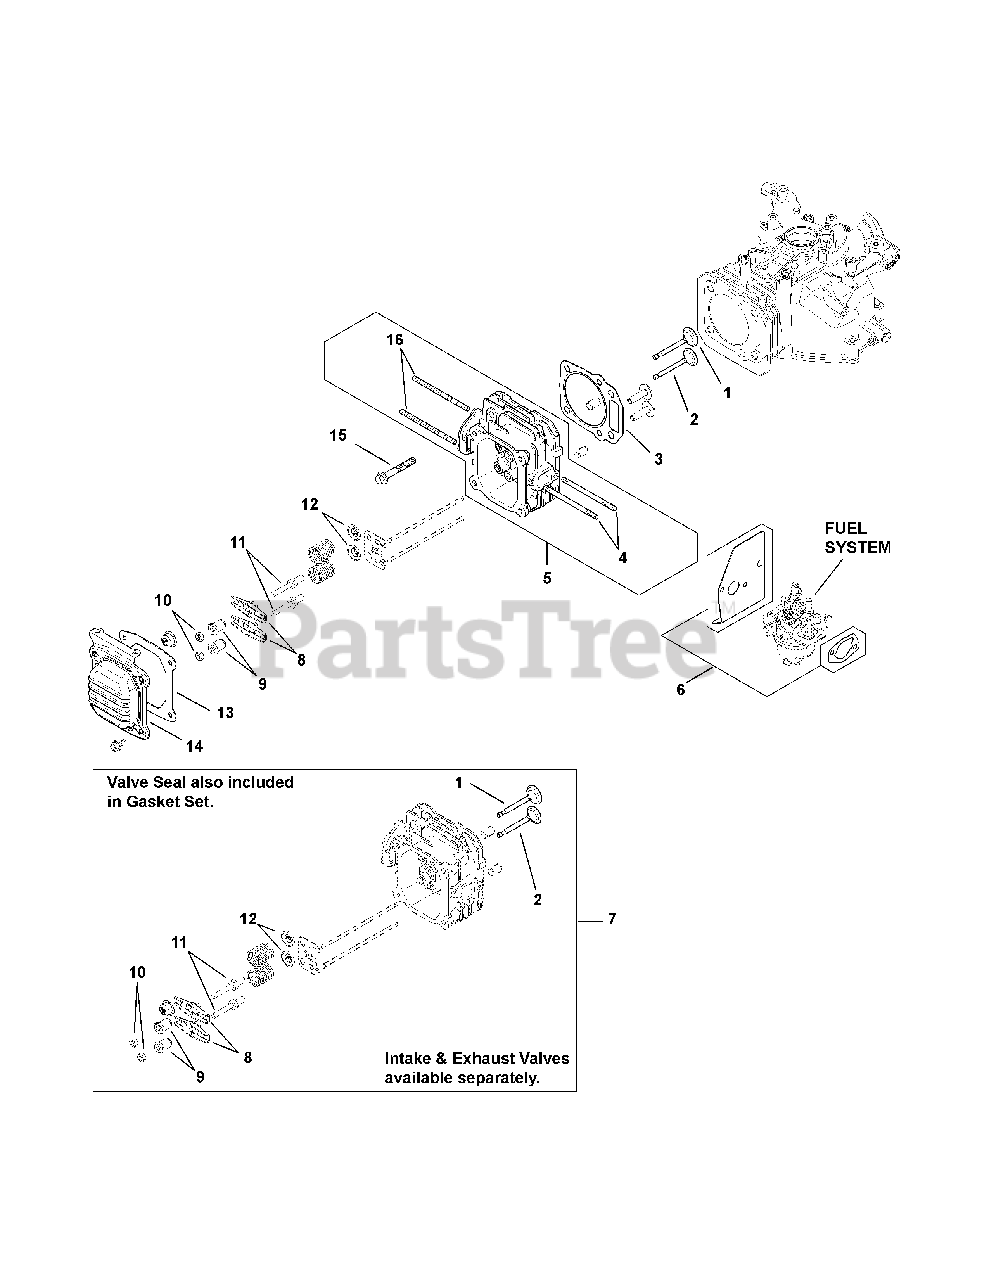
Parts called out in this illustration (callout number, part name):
1	Valve, Intake
2	Valve, Exhaust
3	Kit, Head Gasket
4	Stud, M6X1.0X93
5	Kit, Cylinder Head (Includes 4, 16)
6	Kit, Carburetor Gasket
7	Kit, Valve Train
9	Pivot, Rocker Arm
11	Stud, Rocker Arm
12	Retainer, Valve Spring
13	Gasket, Valve Cover
14	Kit, Valve Cover (Includes 13)
15	Screw, Flg M8X1.25X55
16	Kit, Exhaust Hardware
